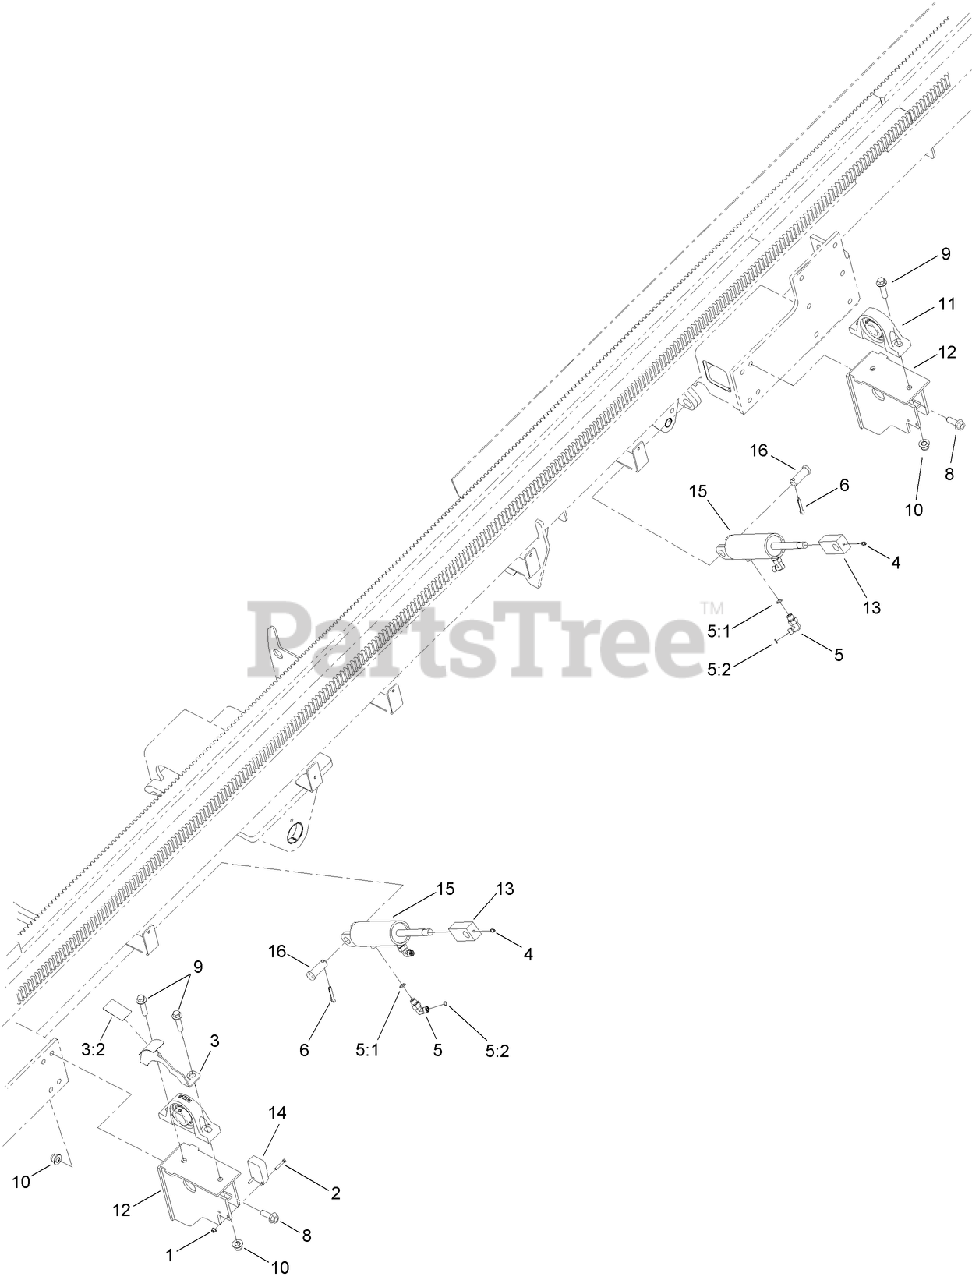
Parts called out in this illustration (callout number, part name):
1	NUT-HF
2	SCREW-HSH
3	ROW INDICATOR ASM
3:2	DECAL-ROW SELECTOR
4	FITTING-GREASE
5	FITTING-ELBOW 90
5:1	O-RING
5:2	O-RING
6	PIN-COTTER
8	SCREW-HFH
9	SCREW-HHF
10	NUT-HHF, LOCK
11	BEARING-PILLOW
12	MOUNT-BEARING
13	EYE-ROD, CYLINDER
14	SWITCH-PROXIMITY
15	HYD CYLINDER ASM
16	PIN-CLEVIS
